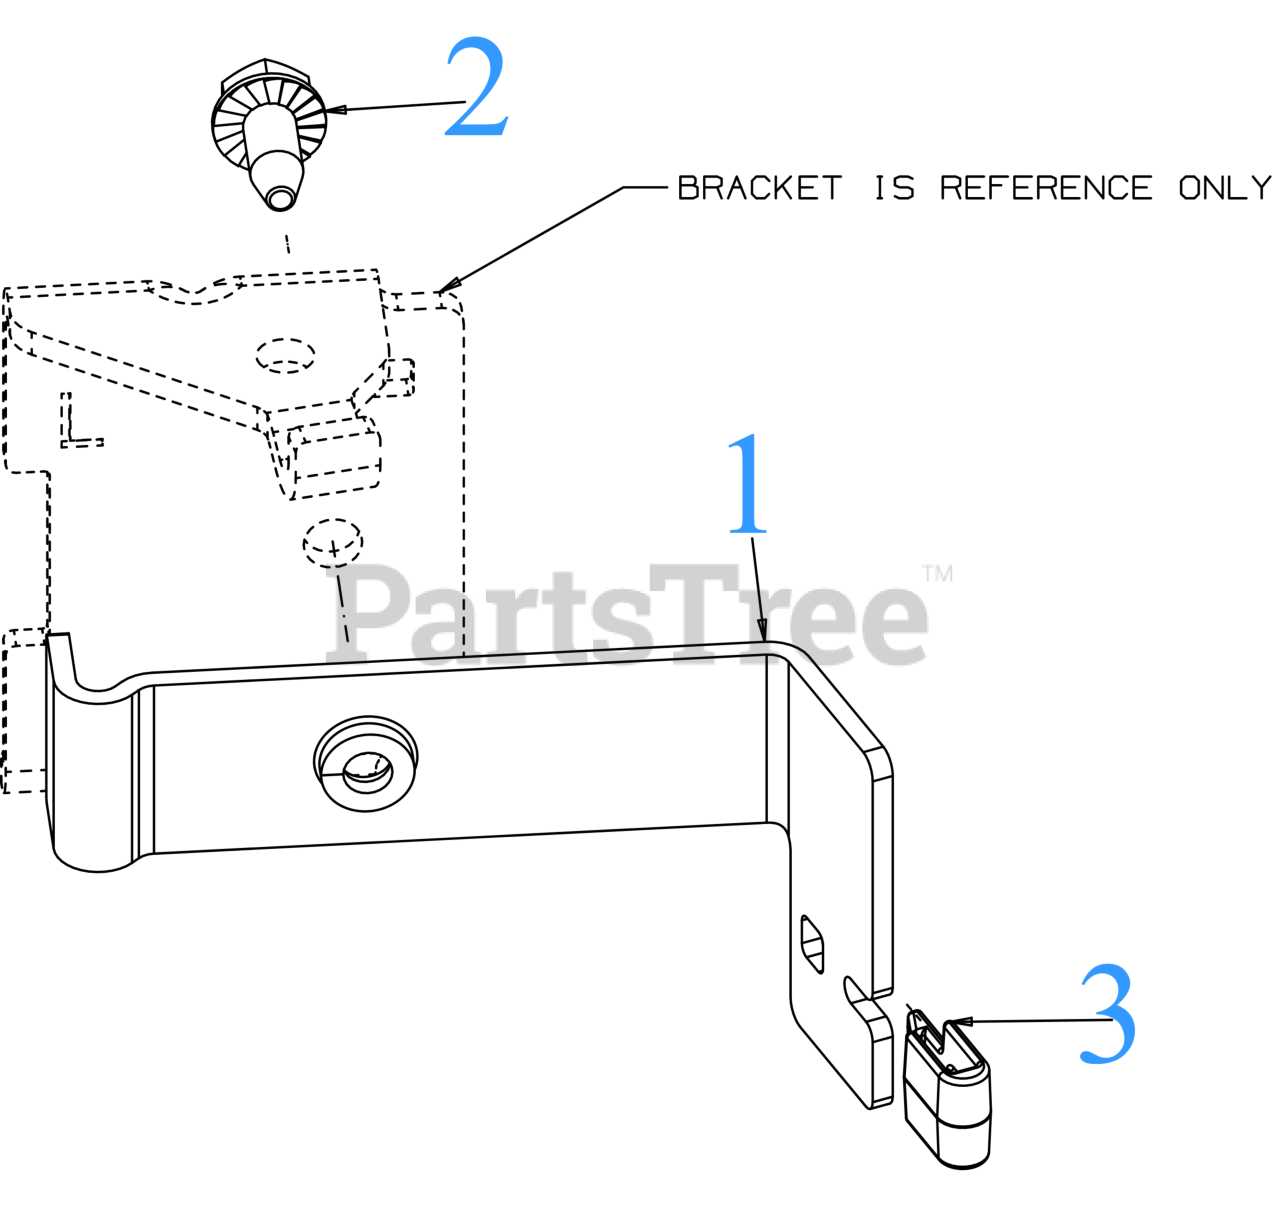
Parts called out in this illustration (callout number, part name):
1	CLUTCH STOP BRACKET
2	SCREW M8-1.25 x .750
3	CLUTCH BRACKET GROMMET
